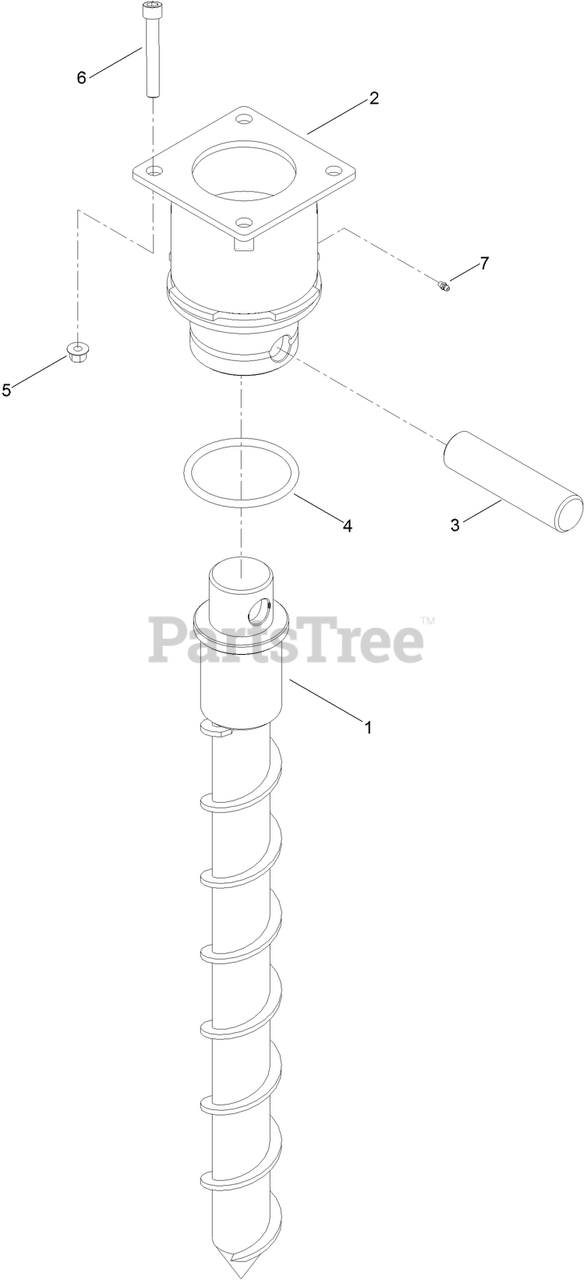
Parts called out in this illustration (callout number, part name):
1	STAKE-DIRT, HD
2	COUPLER-STAKE DOWN
3	PIN-STAKE
4	O-RING
5	NUT-LOCK, HHF
6	SCREW-HSH
7	FITTING-GREASE
